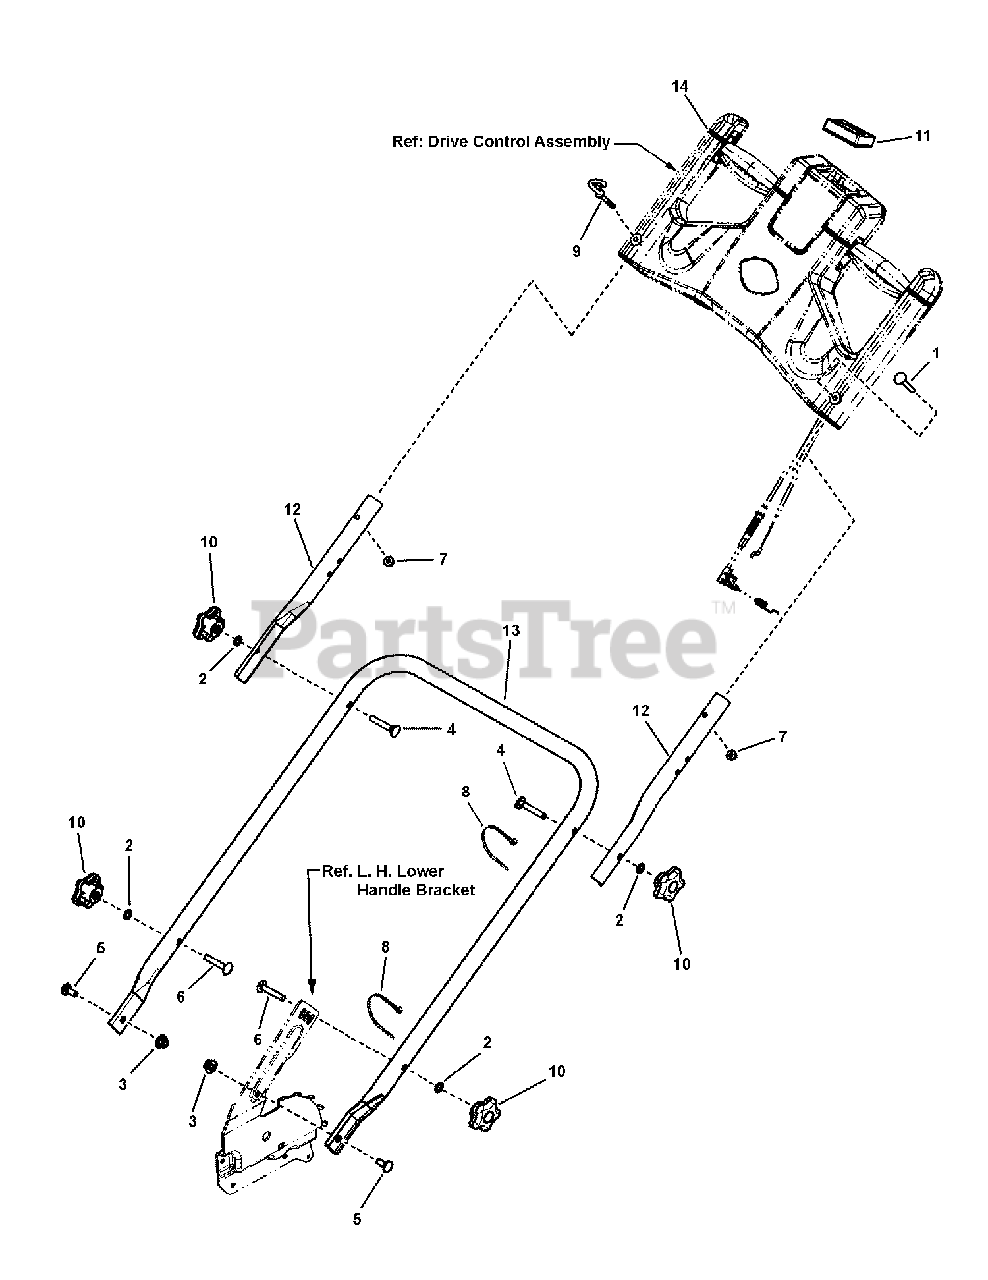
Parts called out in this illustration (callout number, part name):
1	BOLT, 1/4-20 x 1-3/4" Round Head Square Neck, GR 2, YZ
2	WASHER, 5/16" Internal Tooth Lock
3	NUT, 5/16-18 Large Flange Center Lock
4	BOLT, 5/16-18 x 2" Curved Head Square Neck, GR 2
5	BOLT, 5/16-18 x 3/4" Round Head Short Square Neck Carriage, GR 5
6	BOLT, 5/16-18 x 1-3/4" Round Head Square Neck Carriage
7	NUT, 1/4-20 Hex Flange (Esna), YZ
8	WIRE TIE, 11 Inch Standard Black Nylon
9	ROPE GUIDE, (1/4-20 thread)
10	KNOB, Handle, (5/16-18 internal threads) 5-Prong
11	METER, Service Indicator
12	HANDLE, Connecting, 21"/22" WBM
13	HANDLE, Lower
14	ASSEMBLY, Drive Control, MY2010 Front Wheel Drive
